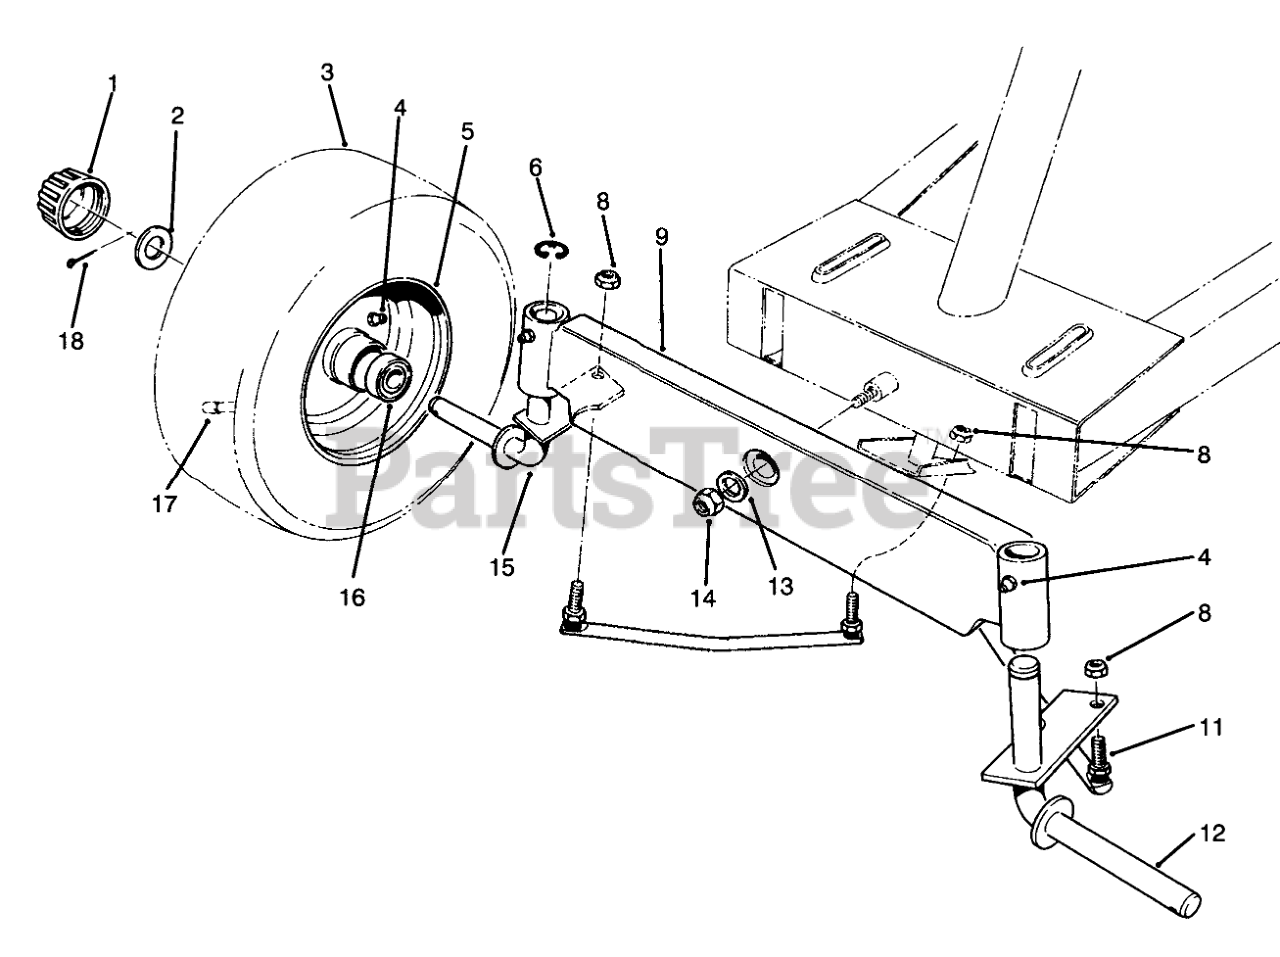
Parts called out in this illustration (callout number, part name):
1	CAP-HUB
2	WASHER-PLAIN
3	TIRE,PNEU.11X4.00X5
4	FITTING-GREASE
6	E-RING
8	NUT-LOCK
9	Axle-Front
11	TIE ROD ASM
12	WHEEL SPDLE WA LH (RED)
13	WASHER-FLAT
14	NUT-LOCK, NI
15	WHEEL SPDLE WA RH (RED)
16	BEARING-WHEEL
17	STEM-VALVE
18	PIN-COTTER
